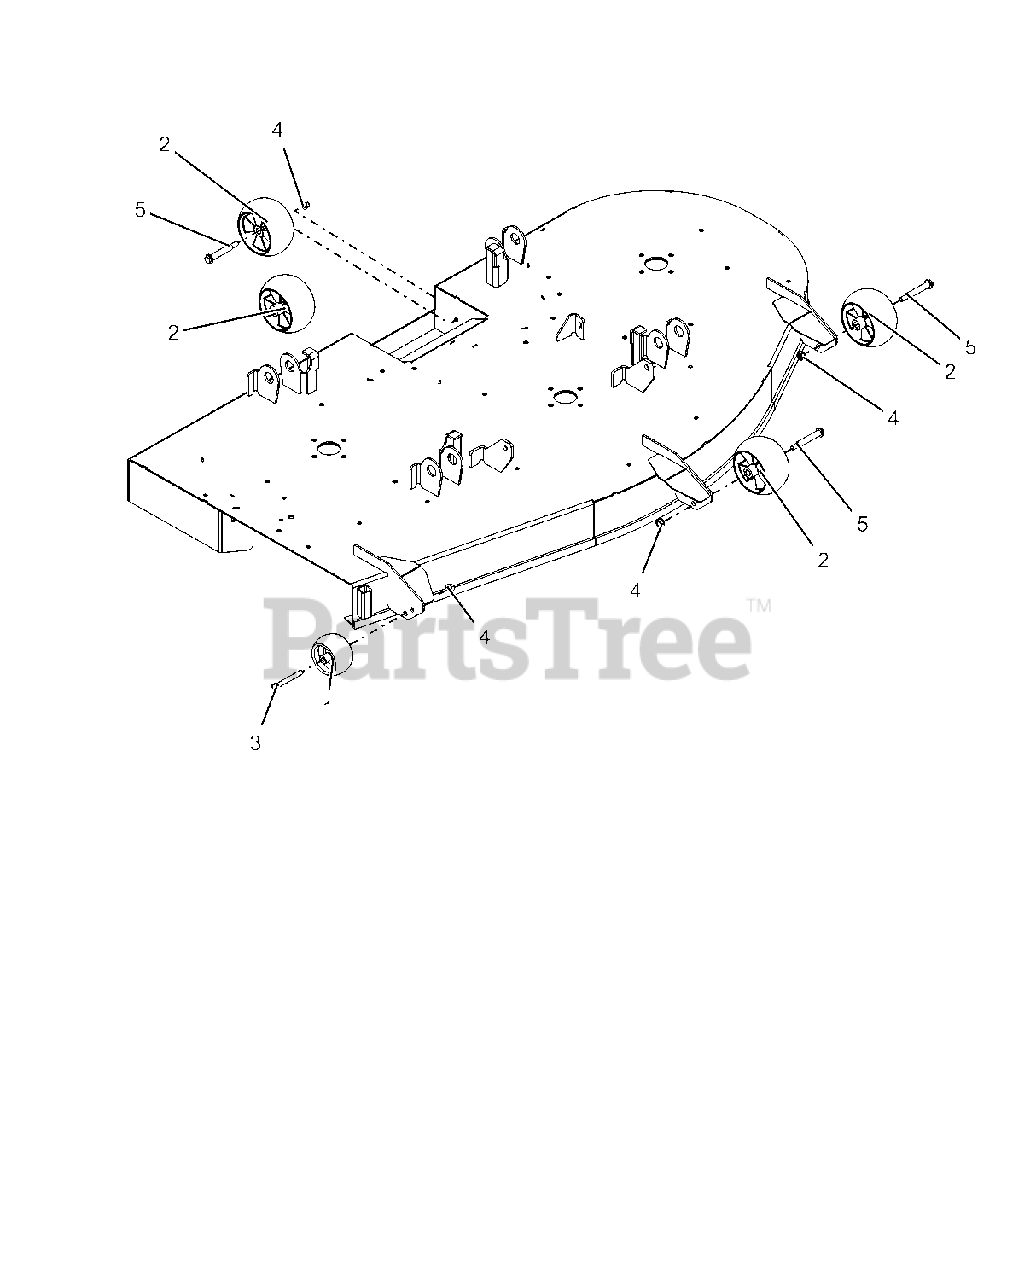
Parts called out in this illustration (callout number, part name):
2	ANTI-SCALP WHEEL - 5X OS
3	BLT-HEX .38-16X3.00 HEX 8 YWZC
4	@NUT-LK-TOP-FLG .38-16 YWZC
5	BLT-SHLDR .38-16X2.50 HWH G5
